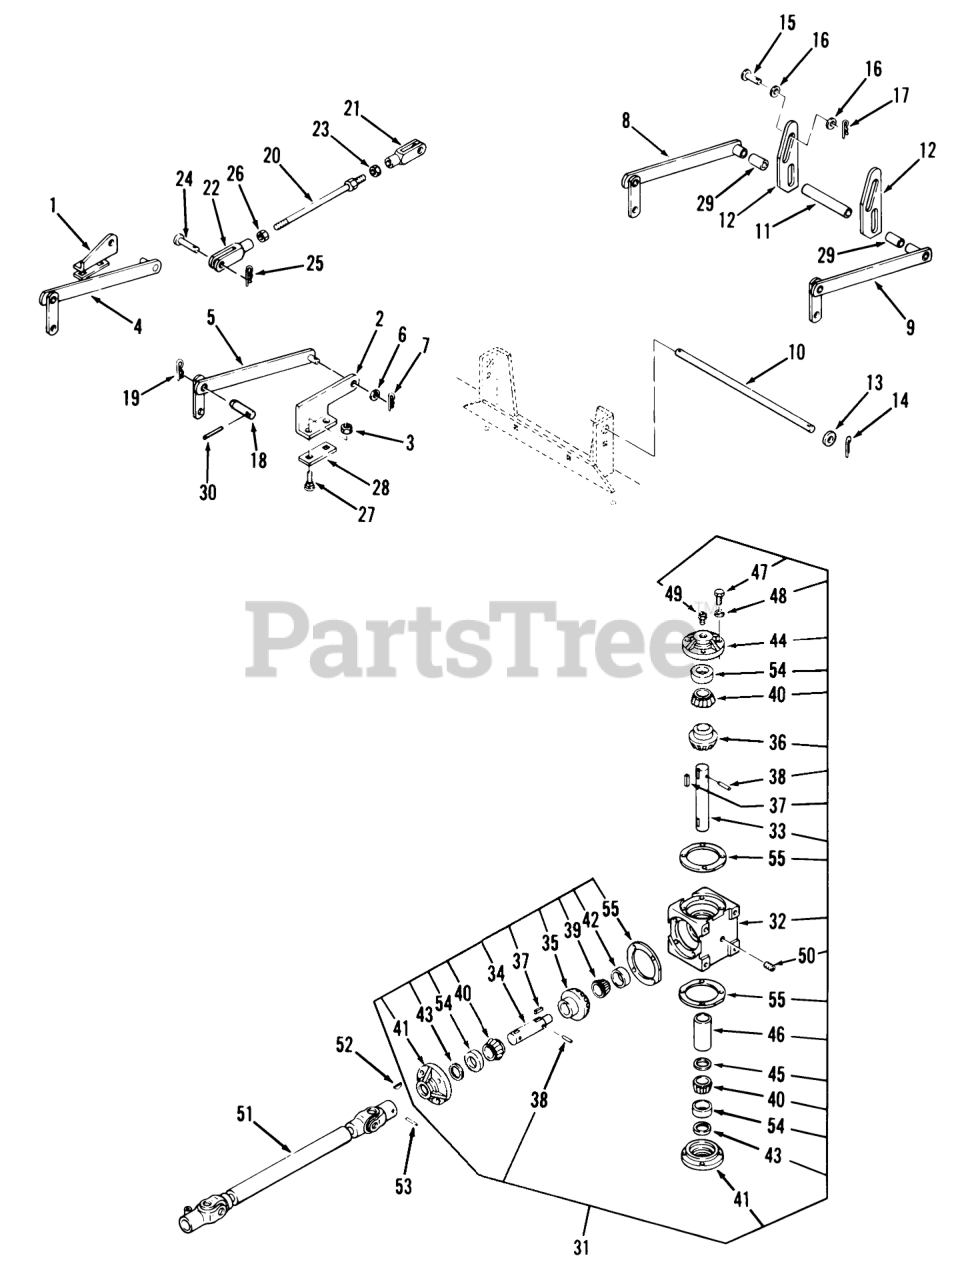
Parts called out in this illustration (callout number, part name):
1	Front R.H. Bracket
2	Front L.H. Bracket
3	Nut
4	Front R.H. Lift
5	Front L.H.Lift
6	Washer
7	Hairpin
8	RH REAR LIFT ASSY
9	Lift Assembly, Left Rear
10	Rear Lift Rod
12	Lift Plate
13	Washer 7/8 SAE
14	PIN-4
15	Clevis Pin 5/8 x 1 1/4
16	WASHER
17	Hairpin
18	Attaching Pin
19	Hairpin
20	Rod Assembly
21	Clevis
22	Clevis (L.H. Thread)
23	Jam Nut
24	CLEVIS PIN
25	Hairpin Cotter
27	Bolt
28	Support Plate
31	Gear Box Assembly
32	Housing
33	Shaft
34	Shaft
35	Toggle
36	Bevel Gear
38	Roll Pin
39	Tapered Roller Bearing
40	Tapered Roller Bearing
41	CAP ASSY-SERVICE ONL
42	Bearing Cup
43	Seal
44	Side Plate Gasket
45	Washer
46	Spacer
47	HHCS
48	Lockwasher
49	Relief Valve
50	Washer
51	SHAFT-PTO DRIVE
52	WOODRUFF KEY 1/4X7/8
53	Spirol Pin 1/4 x 1 3/4
54	CUP-BEARING--SERVICE
55	Gasket, .002 Thick
55	Gasket, .003 Thick
55	Gasket, .005 Thick
55	Gasket, .015 Thick
